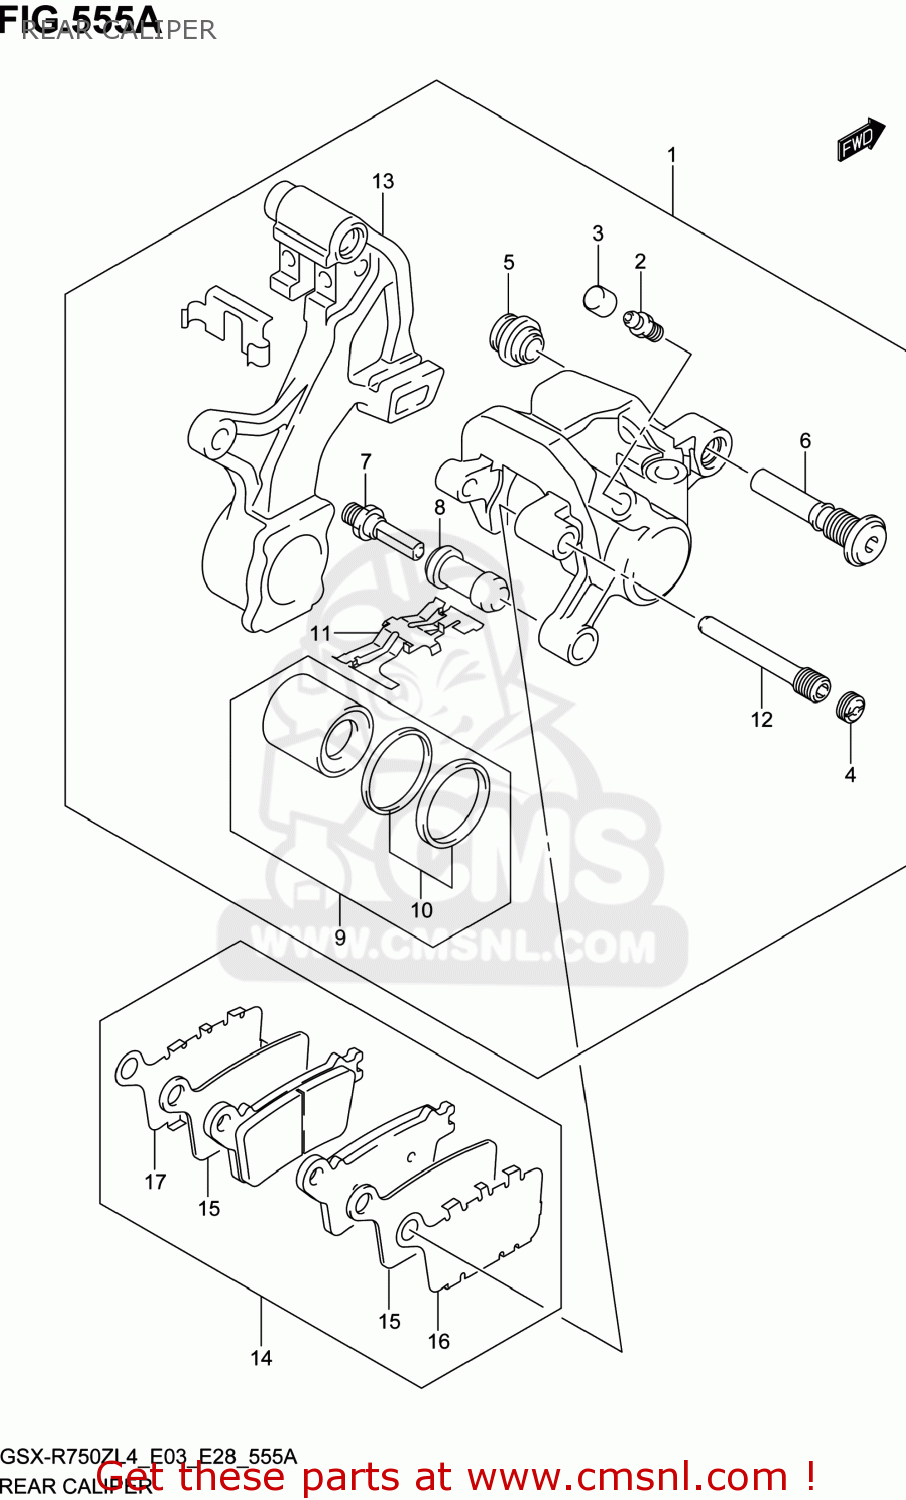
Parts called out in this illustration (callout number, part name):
1	CALIPER ASSY,RR
2	BLEEDER
3	CAP,BLEEDER
4	PLUG,PIN
5	BOOT
6	PIN,BOLT
7	PIN,BOLT
8	BOOT
9	PISTON SET
10	SEAL SET,PISTON
11	SPRING,PAD
12	PIN,PAD
13	BRACKET,RR
14	PAD & SHIM SET (NAS)
15	INSULATOR
16	RETAINER,PAD
17	RETAINER,PAD
